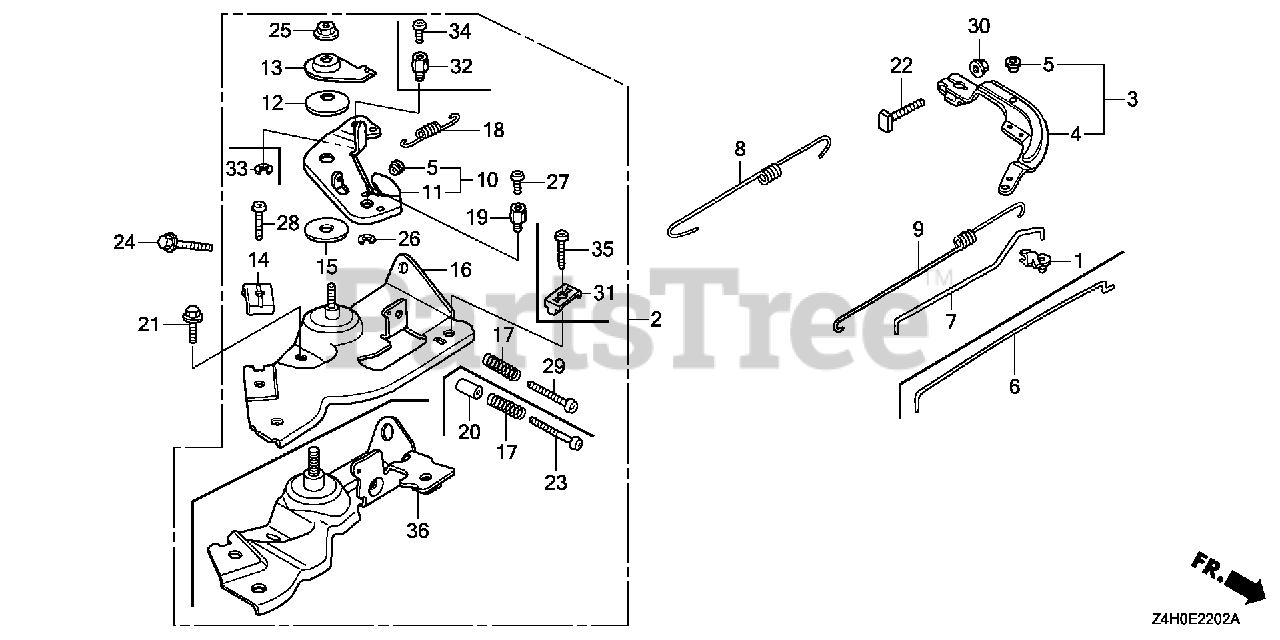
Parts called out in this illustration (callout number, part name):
1	JOINT, ROD
2	CONTROL ASSY.
2	CONTROL ASSY. (COO)(FOR U.S.A.)
4	ARM, GOVERNOR
7	ROD, GOVERNOR
8	SPRING, GOVERNOR
9	SPRING, THROTTLE RETURN
11	LEVER, CONTROL
12	SPRING, LEVER
13	WASHER, CONTROL LEVER
14	HOLDER, CABLE
15	SPACER, CONTROL LEVER
17	SPRING, CONTROL ADJUSTING
18	SPRING, CABLE RETURN
19	HOLDER, WIRE
21	BOLT, FLANGE (6X12) (CT200)
22	BOLT, GOVERNOR ARM
24	BOLT, FLANGE (6X20) (CT200)
25	NUT, SELF-LOCK (6MM)
26	CIRCLIP (5MM)
27	SCREW, PAN (4X6)
28	SCREW, PAN (5X16)
29	SCREW, PAN (5X25)
30	NUT, FLANGE (6MM)
36	BASE, CONTROL
